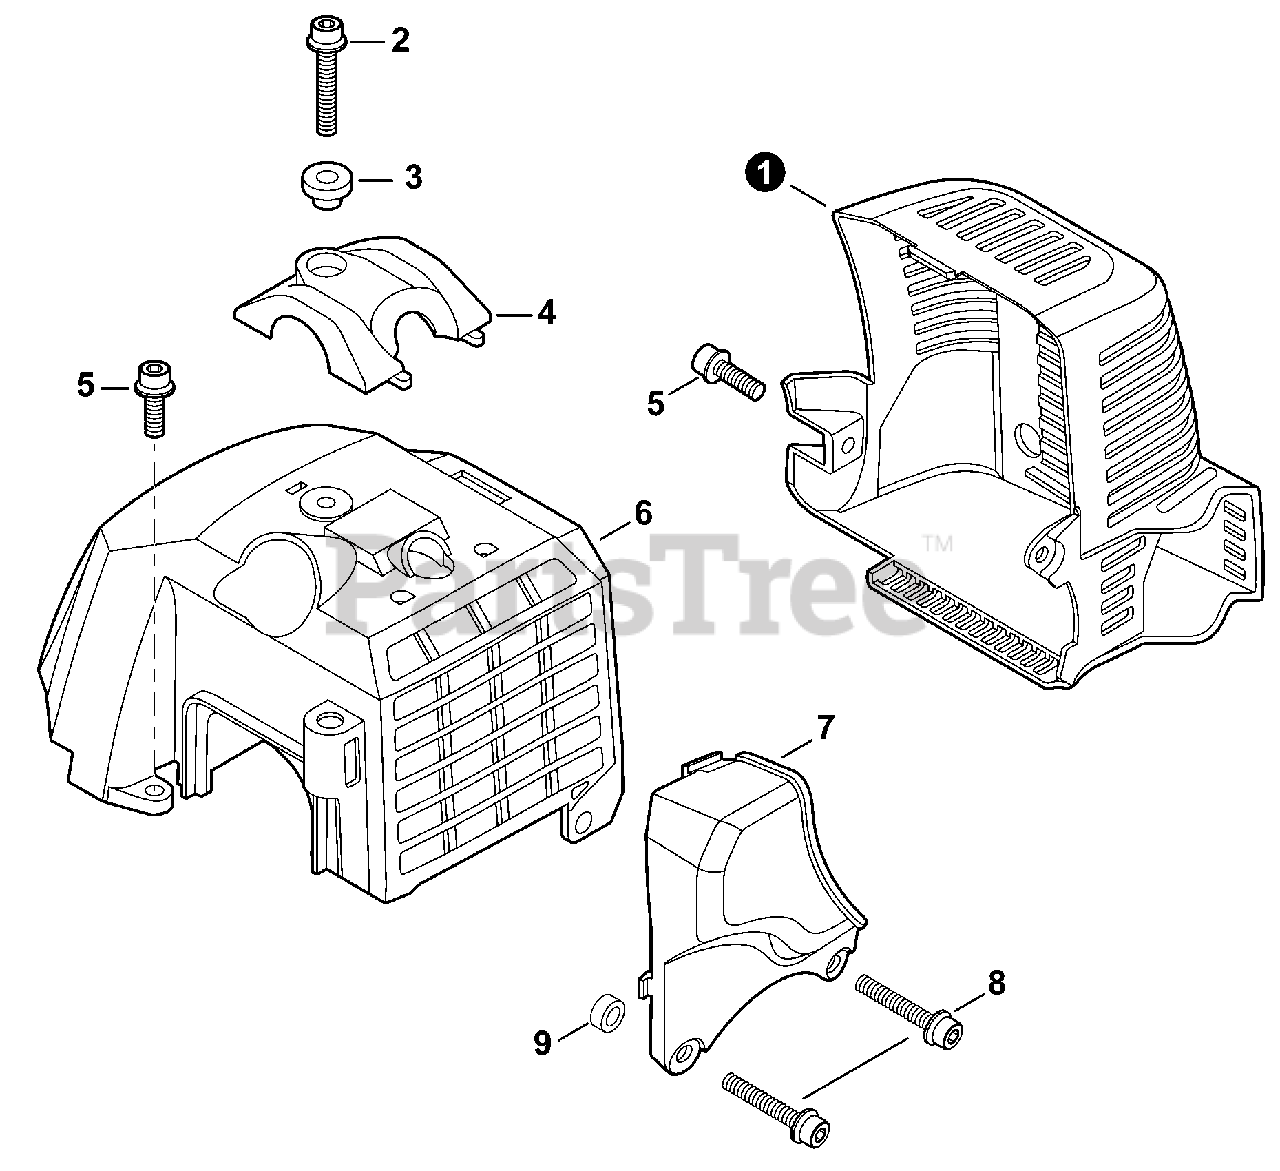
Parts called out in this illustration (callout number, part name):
1	COVER, MUFFLER
2	BOLT 5×20
3	COLLAR 5
4	GUARD, TOP
5	BOLT 5×12
6	COVER, ENGINE
7	DEFLECTOR, HEAT
8	BOLT 5×25
